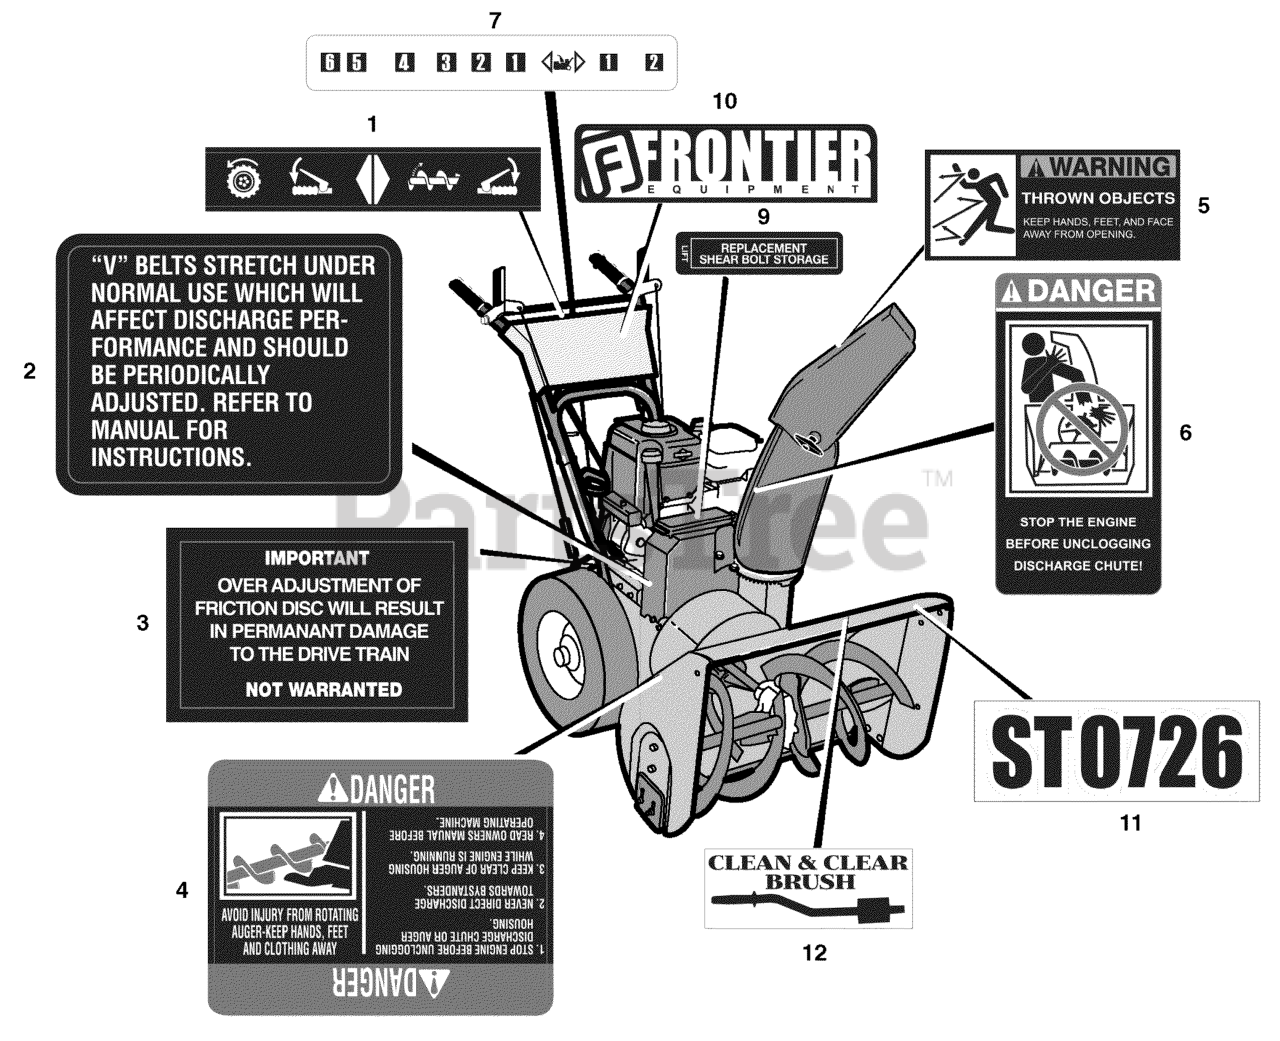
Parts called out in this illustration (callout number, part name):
1	DECAL, HAND CONTROL
2	DECAL, V-BELTS
3	DECAL, OVER ADJUSTMENT
4	DECAL, ROTATING AUGER
5	DECAL, THROWN OBJECTS
6	DECAL, UNCLOGGING CHUTE
7	DECAL, SPEED CONTROL
9	DECAL, SHEAR BOLTS
10	LOGO NAMEPLATE, FRONTIER
11	DECAL, ST0726
12	DECAL, CLEAN & CLEAR BRUSH
